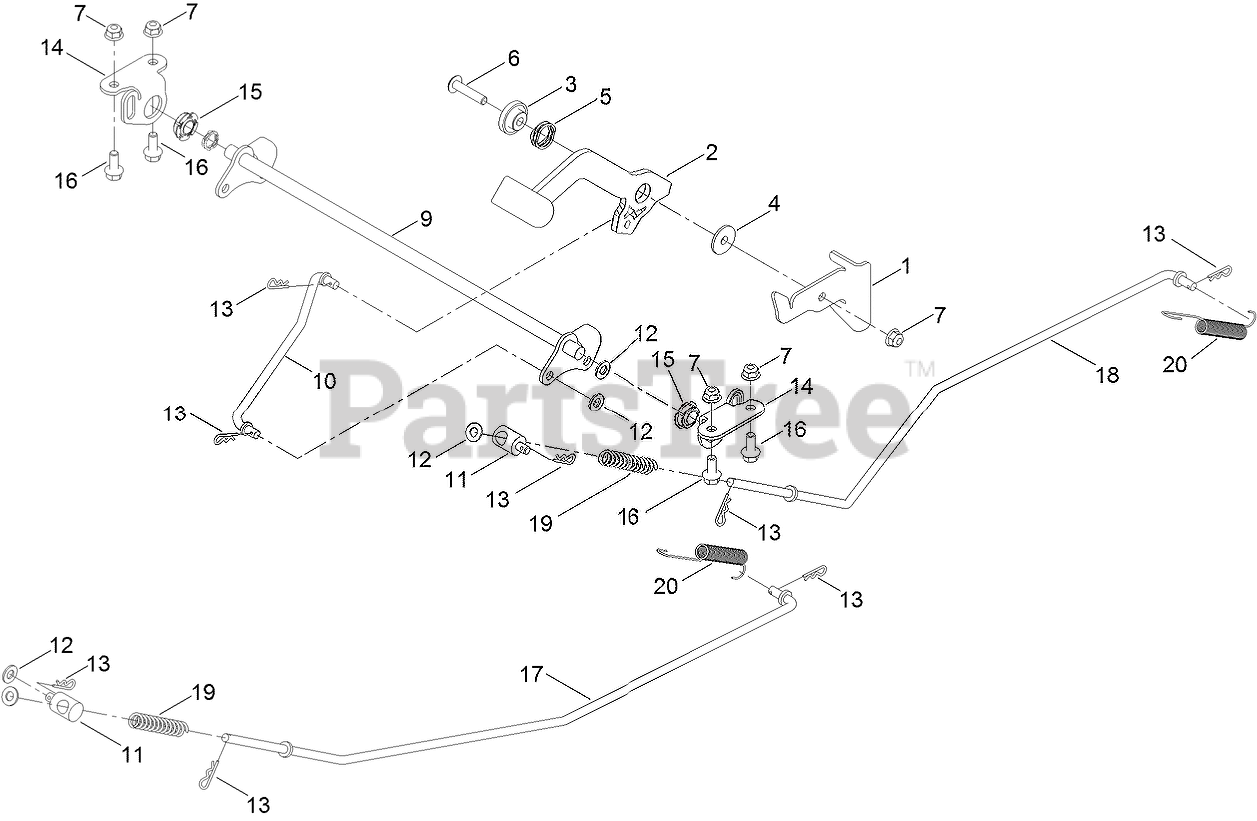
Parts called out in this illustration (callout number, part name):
1	DETENT-BRAKE
2	LEVER-BRAKE
3	BUSHING-FLANGE
4	BUSHING-BRAKE, FLANGED
5	WASHER-WAVE
6	SCREW-TORX
7	NUT-HF, NI
9	BELLCRANK-BRAKE
10	ROD-BRAKE, INTERMEDIATE
11	FITTING-ROD
12	WASHER-PLAIN
14	PLATE-SUPPORT, BELLCRANK
15	BEARING-SPHERICAL
16	SCREW-HHF
17	ROD-BRAKE, RH
18	ROD-BRAKE, LH
19	SPRING-RETURN, NEUTRAL
20	SPRING-EXTENSION
